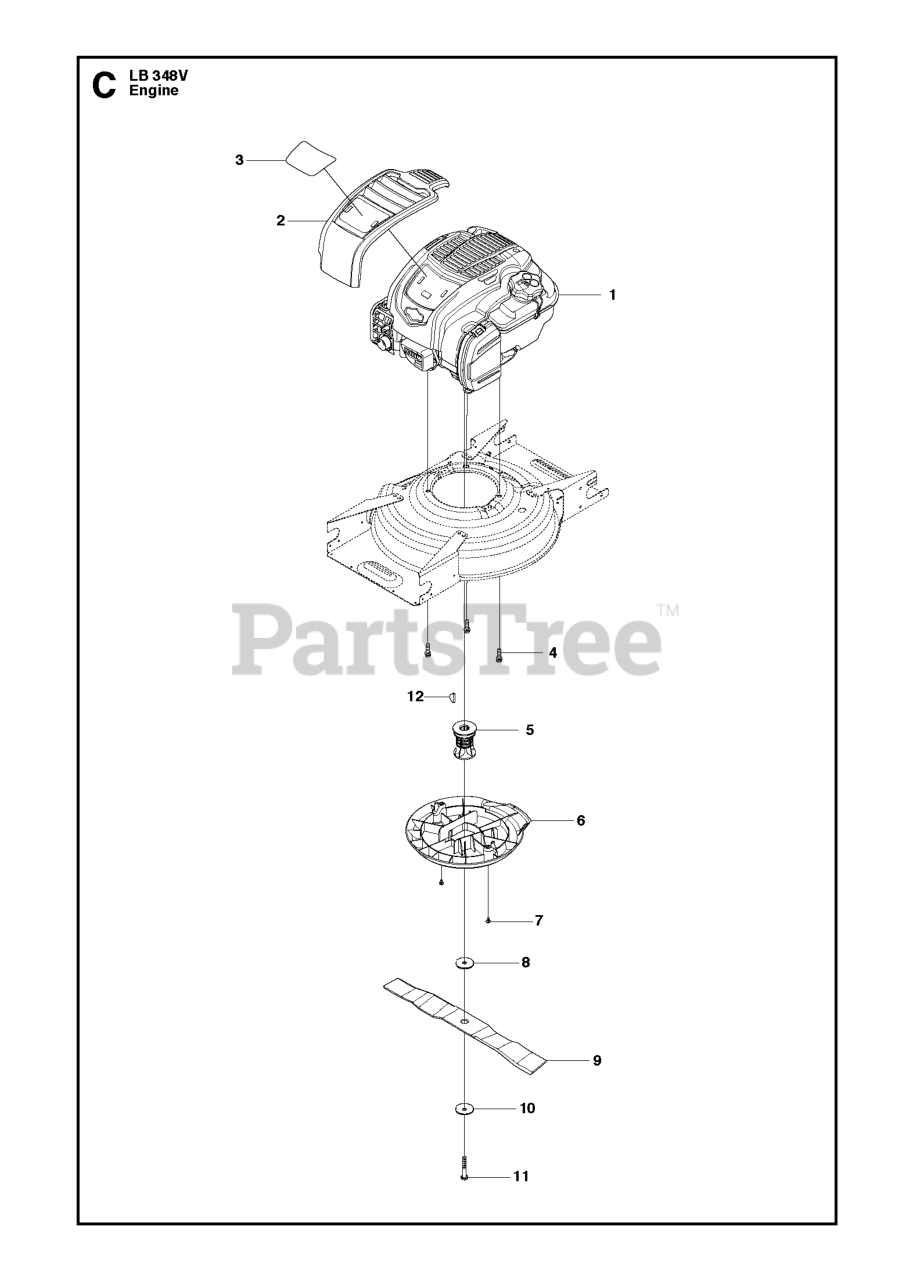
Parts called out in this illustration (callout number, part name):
4	BOLT 3/8-16X1-1/8
6	BELT COVER A009-2
10	SPRINGS
